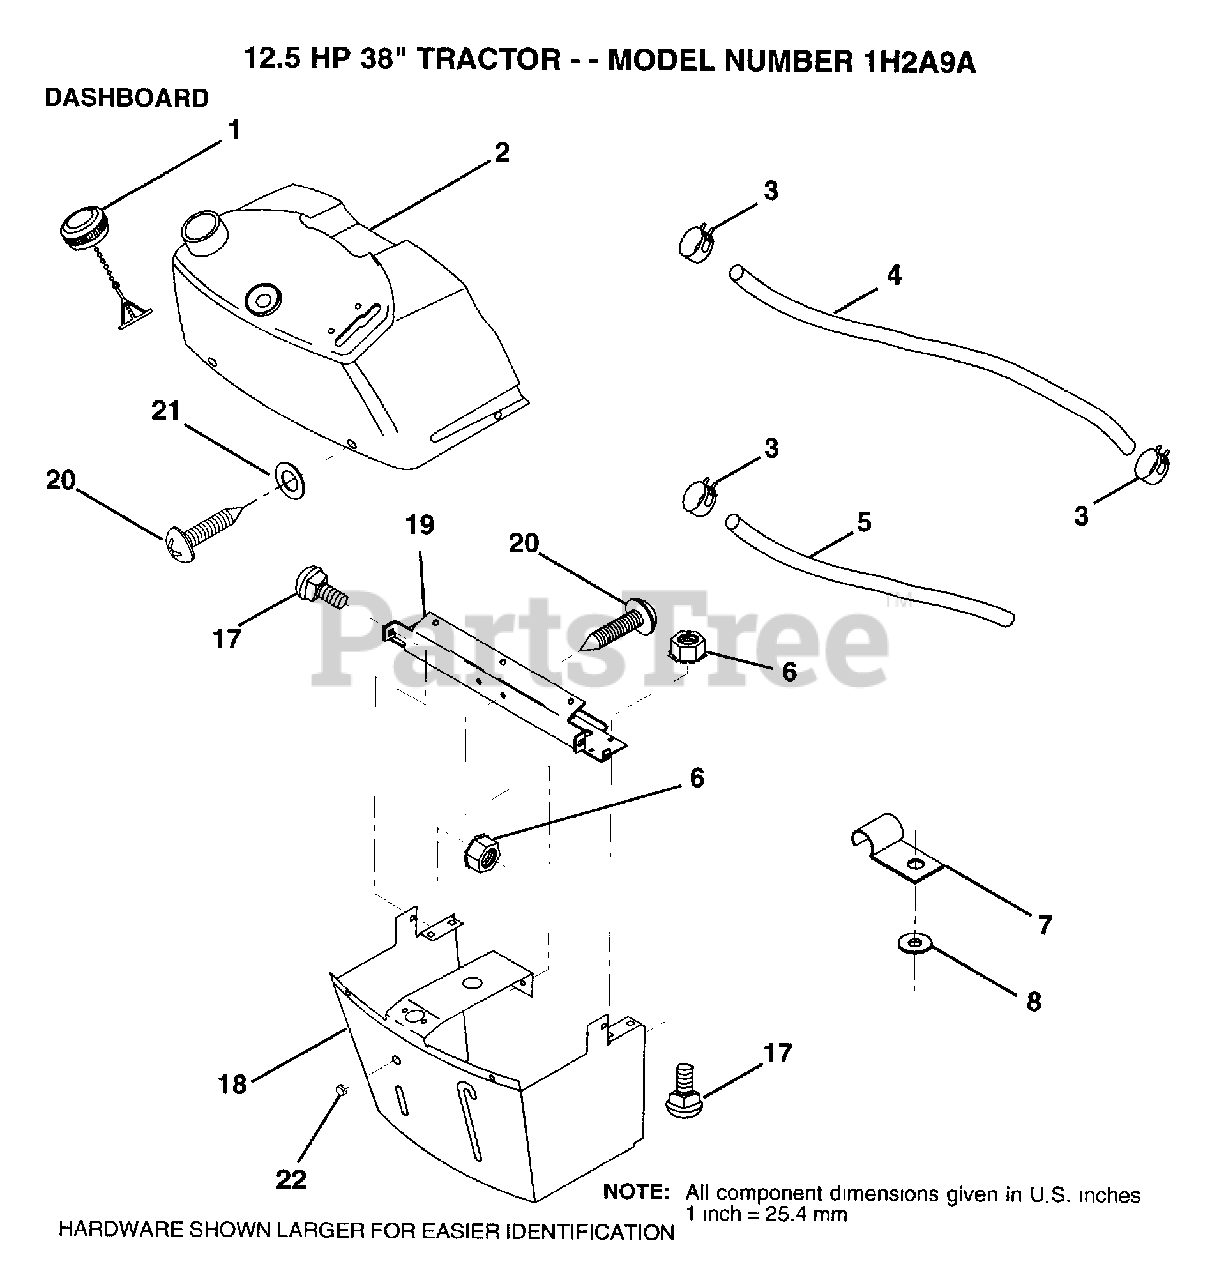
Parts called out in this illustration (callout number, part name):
1	CAP.FUEL.N/VENT
2	TANK.ASM.DASH.LR
3	HOSE CLAMP
5	FUEL LINE T
6	NUT
7	CLIP T
8	WASHER PM
17	BOLT
18	SUPT ASM DASH
19	CROSS BRACE
22	PLUG DOME
